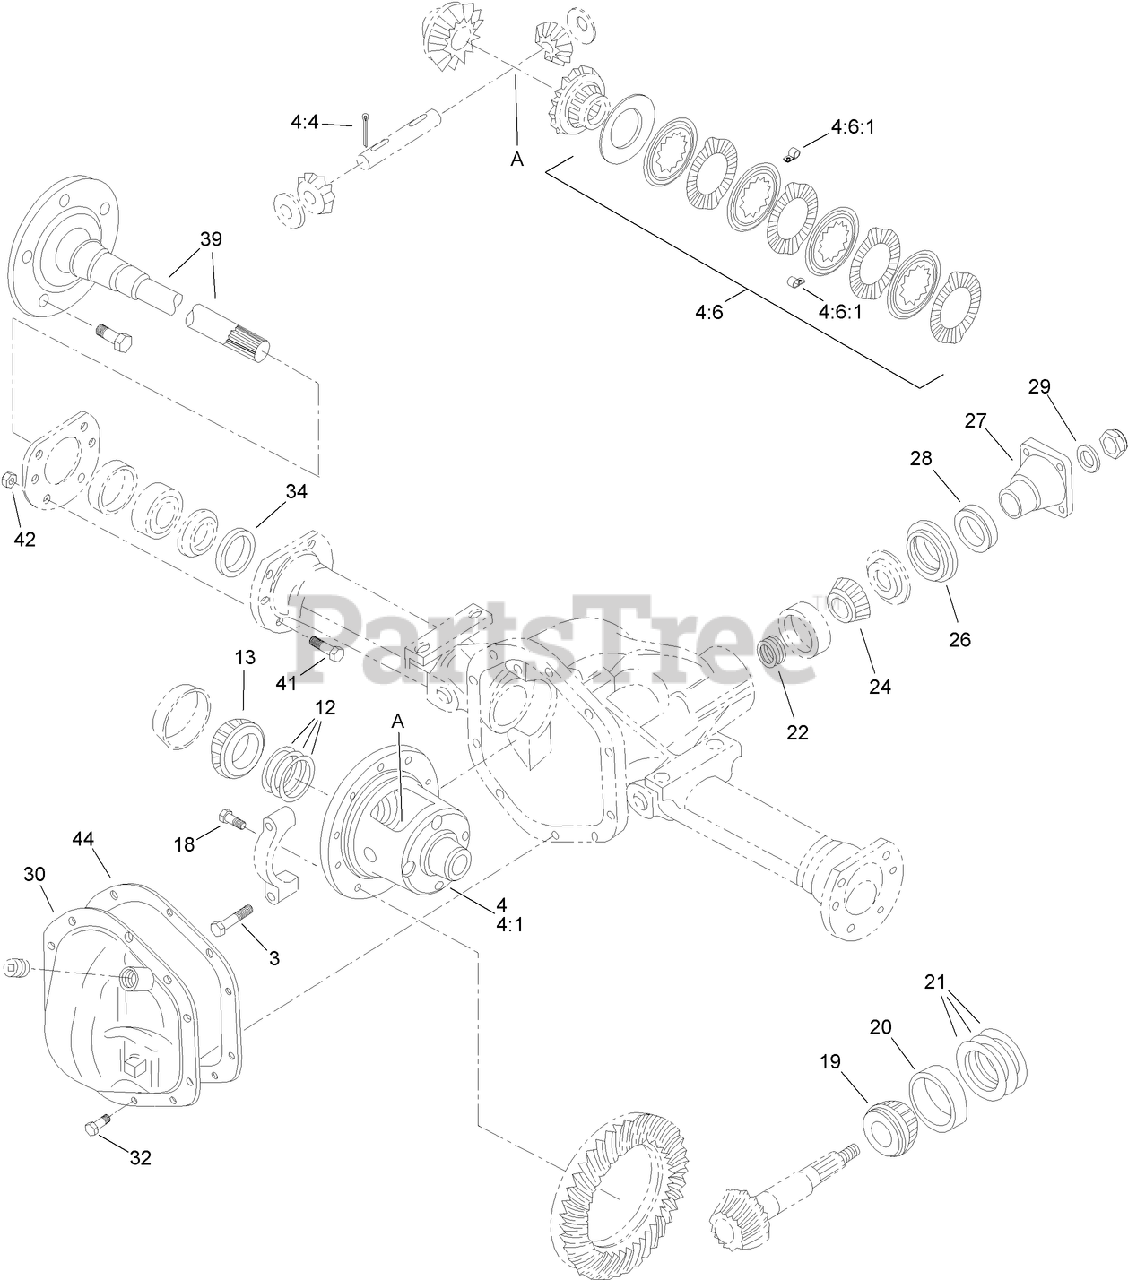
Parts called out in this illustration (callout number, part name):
3	BOLT
4	CASE ASM
4:4	PIN-SPRING, SLOTTED
4:6	DIFFERENTIAL DISC KIT (MATCHED SET)
13	BEARING-TAPER
19	BEARING-TAPER
20	CUP-BEARING
24	BEARING-TAPER
27	END-YOKE
28	SLINGER
30	COVER
42	NUT-HEX
44	MAKER-GASKET
